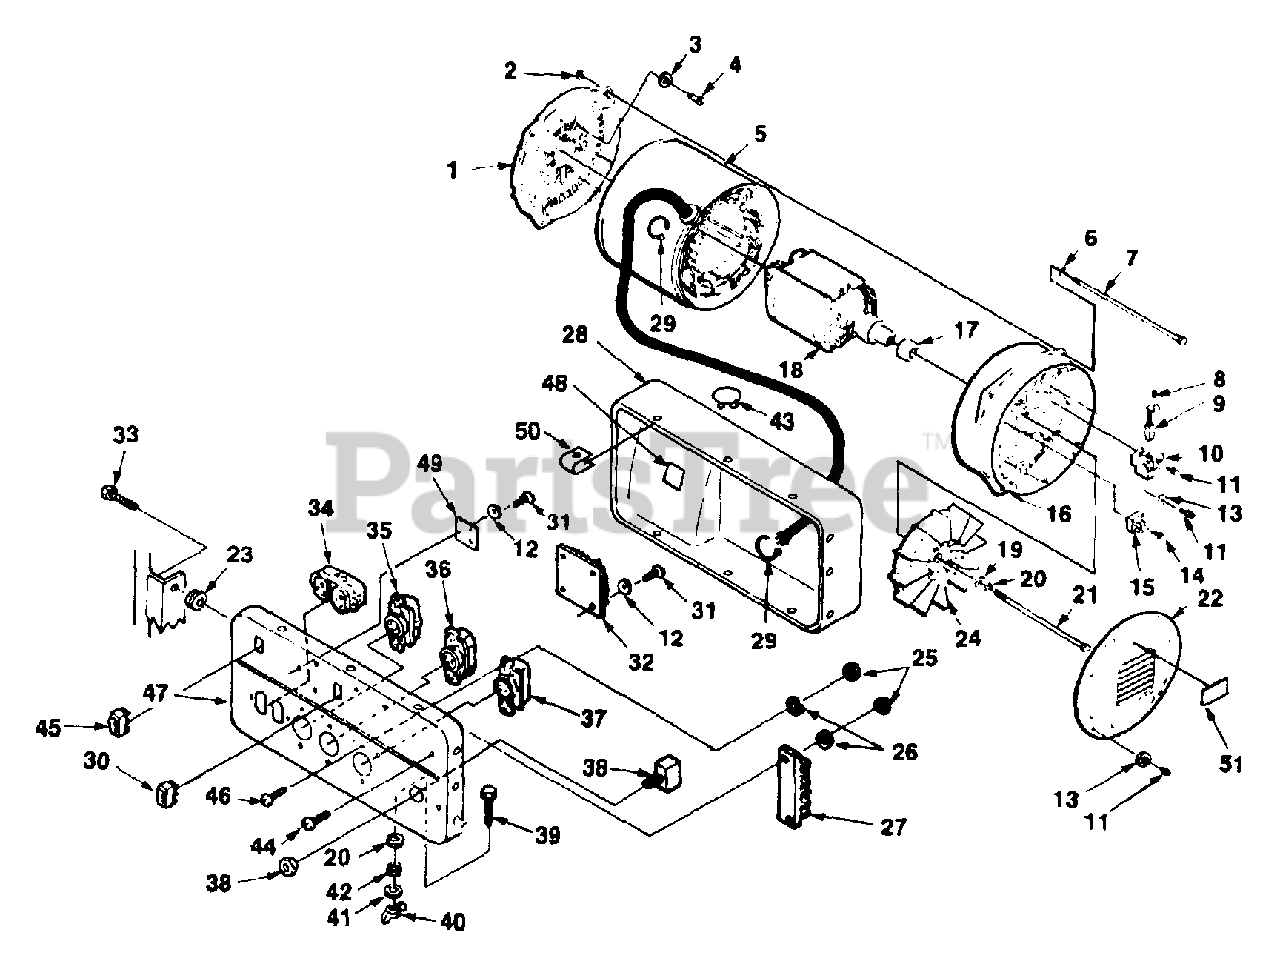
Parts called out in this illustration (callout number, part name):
1	END BELL
2	NUT-Hex (1/4-20)
3	WASHER-Lock
4	SCREW-Hex Hd. (3/8-16 X 7/8")
5	STATOR SHELL
6	WASHER-Lock/Int. (1/4")
7	BOLT-Stator
8	SCREW-Machine Pan Hd. (8-32 X 3/8")
10	BRUSH HOLDER
11	SCREW-Thread Rolling (8-32 X 1/2")
12	WASHER-Flat (#8)
13	WASHER-Lock (#8)
14	SCREW-Hex Tap (8-32 X 3/4")
15	RECTIFIER
16	BRUSH HEAD
17	BEARING
19	WASHER-Flat (5/16)
20	WASHER-Lock (5/16)
21	BOLT-Rotor
22	BRUSH HEAD COVER
23	GROMMET
25	NUT-Hex (8-32)
26	WASHER-Lock (#8)
27	BLOCK-Terminal
28	PANEL-Cover
29	CABLE TIE
30	SWITCH (DPDT)
31	SCREW-Pan Hd. (#8-32 X 1/2")
32	VOLTAGE REGULATOR
33	SCREW-Shoulder
34	RECEPTACLE, GFCI (Nema 5-15R)
35	RECEPTACLE-Locking (Nema L5-20R)
36	RECEPTACLE-Locking (Nema L5-30R)
37	RECEPTACLE-Locking (Nema L14-20R)
38	CIRCUIT BREAKER-2.5 Amp
39	SCREW-Hex Hd. (5/16-18 X 1)
40	NUT-Wing (5/16-18)
41	WASHER-Lock (5/16)
42	NUT-Hex (5/16-18)
43	CLAMP-Cable
44	SCREW-Pan Hd. (8/32 X 5/8")
45	SWITCH-Rocker
46	SCREW-Machine Pan (8-32 X 3/8")
47	CONTROL PANEL
48	DECAL-Schematic
49	IDLE CONTROL
50	NUT-Speed
51	DECAL-Warning
